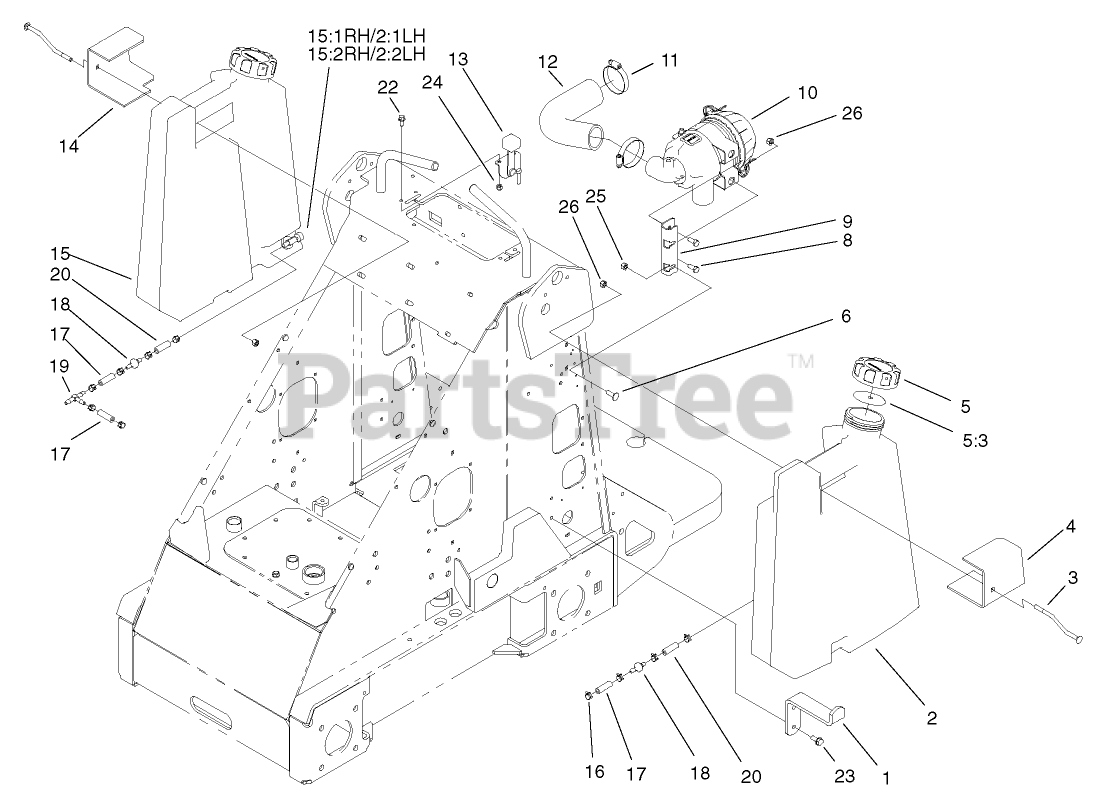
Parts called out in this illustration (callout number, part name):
1	MOUNT-BOTTOM, TANK
2	FUEL TANK ASM, GAS LH
2:1	BUSHING
2:2	VALVE-FUEL
3	BOLT-MOUNT
4	PLATE-MOUNT, LEFT
5	CAP-FUEL, GAS
5:3	GASKET-VENTED
6	BOLT-CARR
8	SCREW-HH
9	MOUNT-CLEANER, AIR
10	AIR CLEANER ASM
11	CLAMP-HOSE
12	HOSE-AIR
13	CONTROL-CHOKE / THROTTLE
14	PLATE-MOUNT
15	RH FUEL TANK ASM
15:1	BUSHING
15:2	VALVE-FUEL
16	CLAMP-HOSE
17	HOSE-FUEL
18	VALVE-CHECK, FUEL
19	FITTING-TEE, BARBED
20	HOSE-FUEL
22	SCREW-HHF
23	SCREW-HWHTF
24	NUT-LOCK, NI
25	NUT-HF
26	NUT-LOCK, NI
